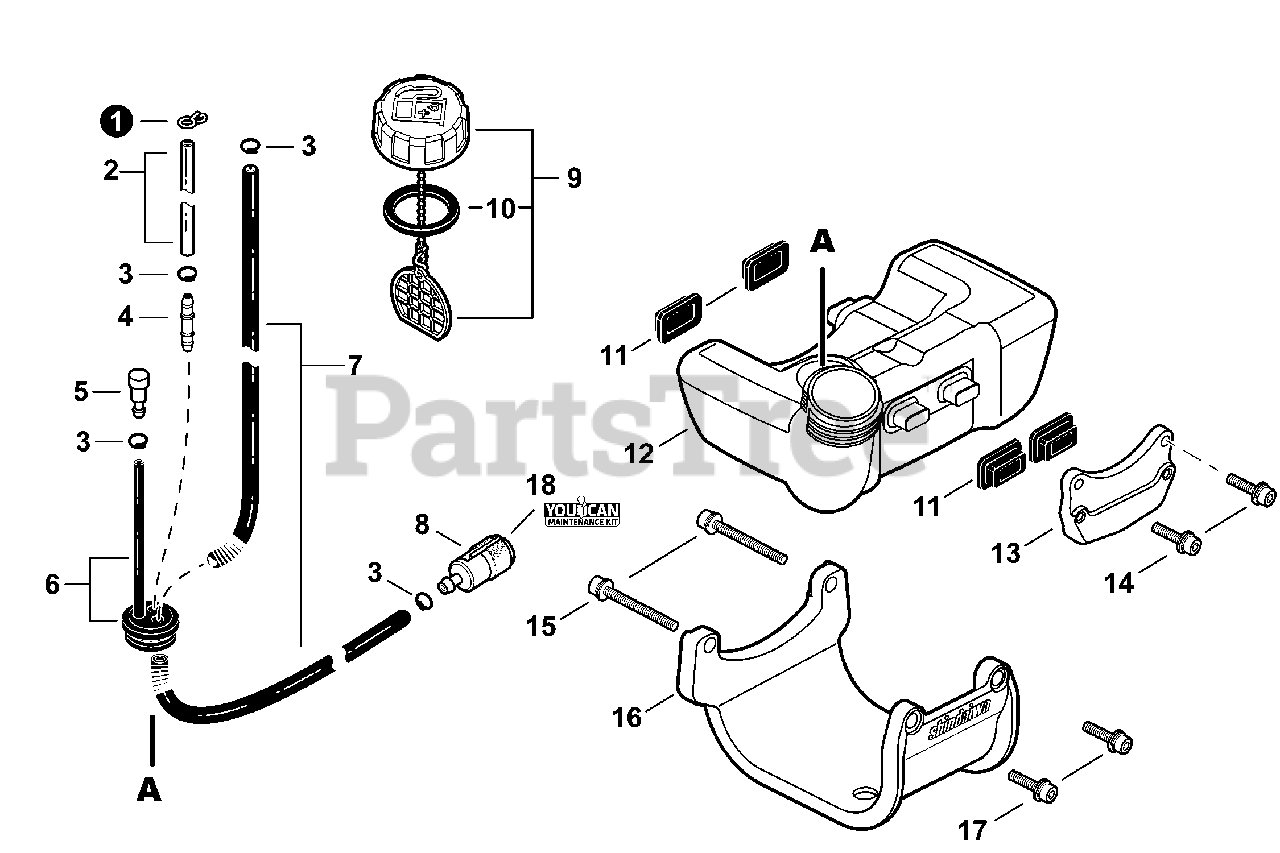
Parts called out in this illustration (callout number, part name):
1	CLIP, SPRING Ø5.2
2	PIPE, FUEL RETURN
3	CLIP Ø6
4	CONNECTOR, PIPE
5	VENT ASSY
6	GROMMET, FUEL W/VENT PIPE
7	PIPE, FUEL 3.3×6×160
8	FILTER, FUEL
9	CAP ASSY, FUEL
10	GASKET, FUEL CAP
11	CUSHION, FUEL TANK
12	TANK, FUEL
13	BRACKET, METAL FUEL TANK
14	BOLT, ADHESIVE M5×20
15	BOLT M5×40
16	GUARD, PLASTIC FUEL TANK
17	BOLT M5×20
18	TUNE-UP KIT - YOUCANT
